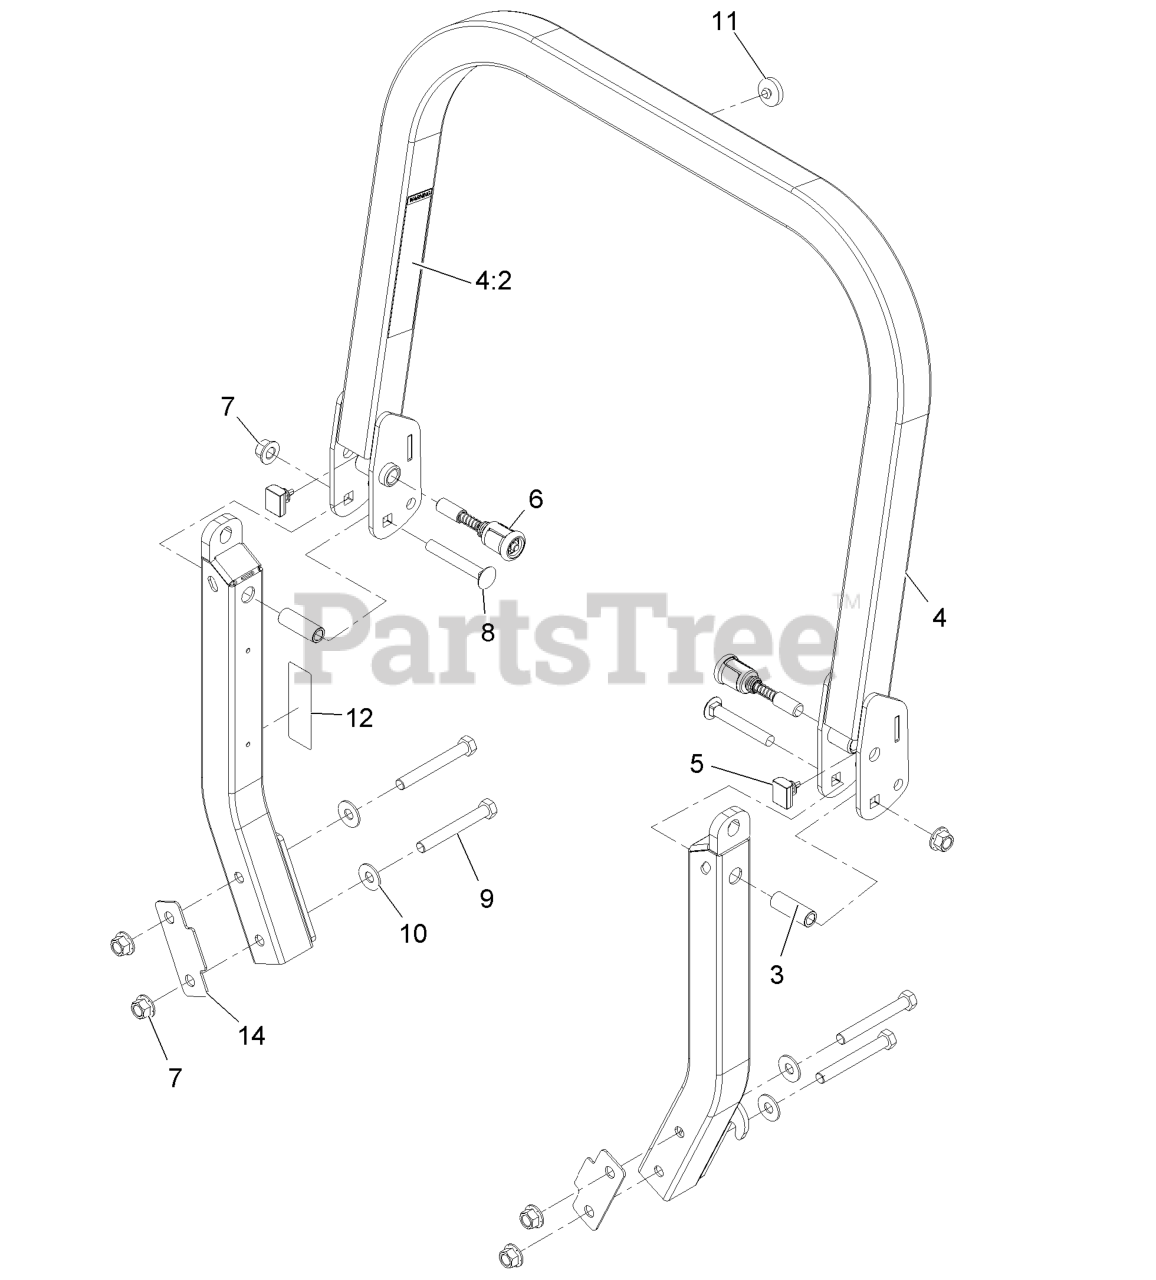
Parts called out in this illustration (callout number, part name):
4	UPPER ROPS ASM
4:2	DECAL-WARNING, FOLDING RO
5	BUMPER-ROPS
6	PIN-SPRING
7	Nut-Lock 1/2-13
8	SCREW-CARR
9	SCREW-HH
10	WASHER-SPRING
11	BUMPER-PUSH-IN, RUBBER
12	DECAL-CAUTION
